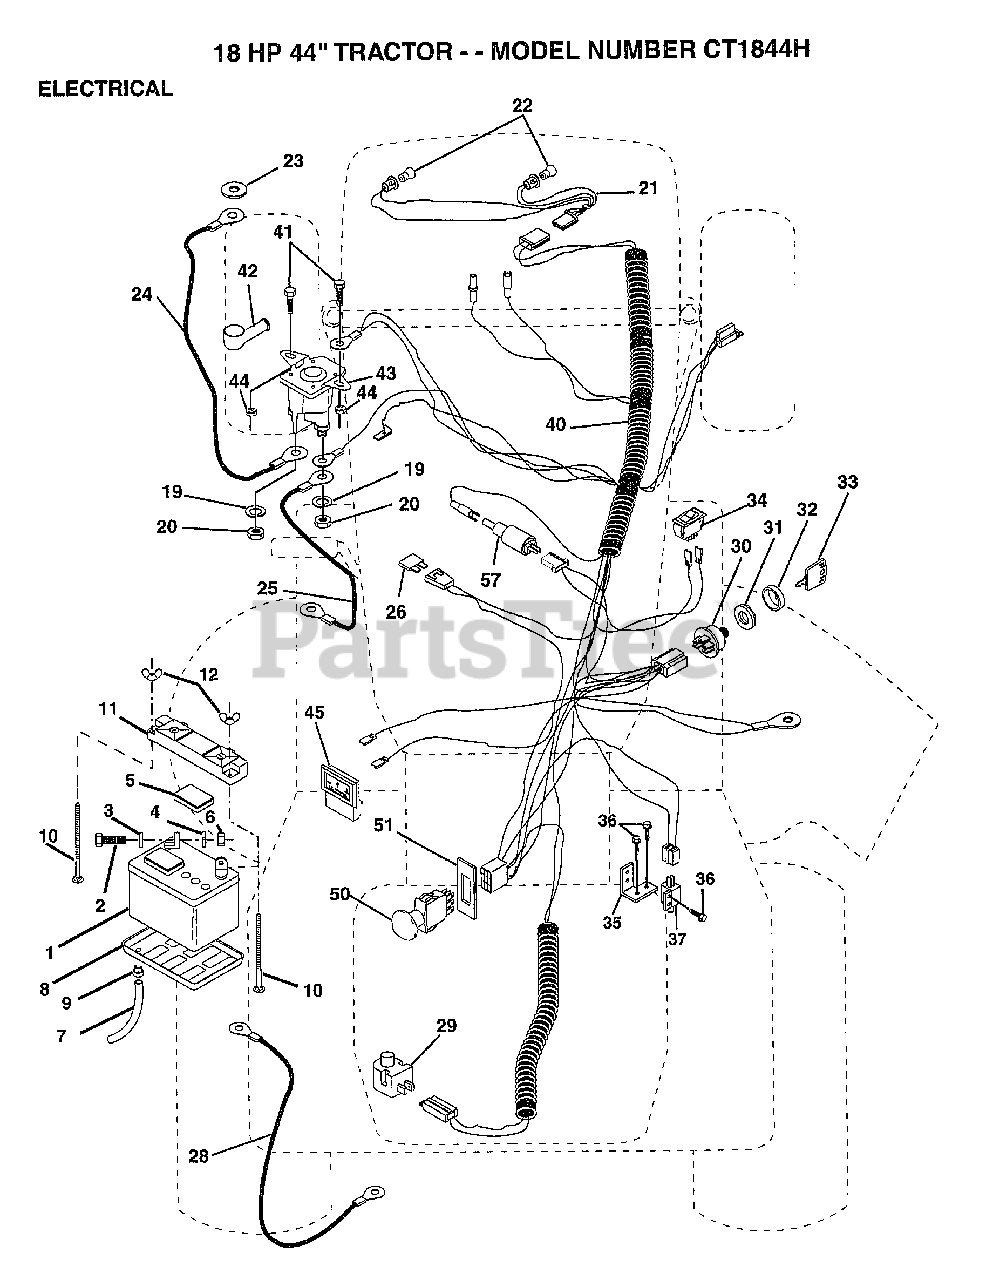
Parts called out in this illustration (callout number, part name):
2	BOLT LT
3	WASHER
4	LOCKWASHER
5	"CAP,BATTERY "
7	"DRAIN TU T, BATT"
8	"TRAY T, BATTERY"
9	HOSE CLAMP T
10	BOLT
20	NUT
21	"HARNESS,LIGHT SOC"
22	HEADLAMP BULB
23	LOCKWASHER
24	"CABLE T, BATTERY"
25	CABLE-BATTERY T
26	FUSE HYT
28	CABLE T
29	SWITCH SEAT
32	COVER KEY SWITCH
33	KEY MLD GEN DELTA
34	SWITCH LT
35	BRACKET LT
36	SCREW
37	SWITCH-INTER. GT
40	HARNESS.IGN.PTO.
41	BOLT HXHD FIN
44	NUT HXKEP 1/4X20
51	RING RETAIN PTO
57	DIODE ASM.
